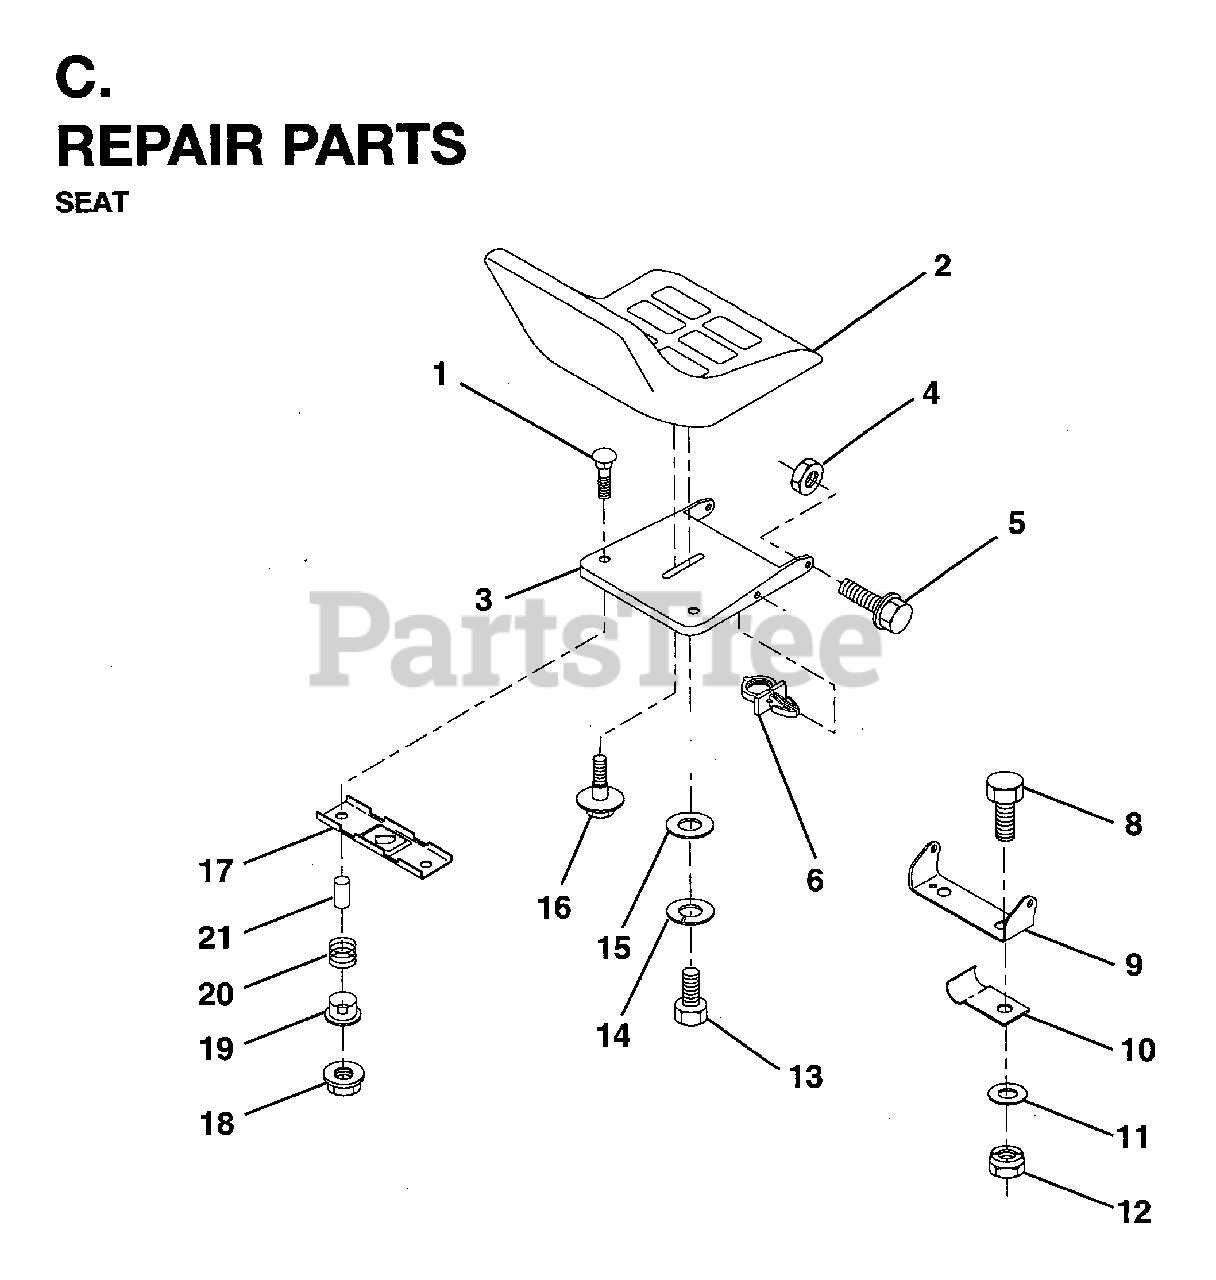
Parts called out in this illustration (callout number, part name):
1	BOLT CARRIAGE 1/4-20X1 3/8
2	SEAT
3	SEAT PAN
4	NUT.71038.31-18.HEX.NYLOCK
6	PUSH CLIP
9	SEAT PIVOT BRKT
10	CLIP,INSULATOR
11	WASHER 12/32X2X10GA
12	LOCKNUT
13	BOLT
14	LOCKWASHER
16	BOLT,SHOULD
17	BRKT SWITCH
18	NUT.CROWNLOCK.1/4
21	SPACER SPLIT 28X.96
